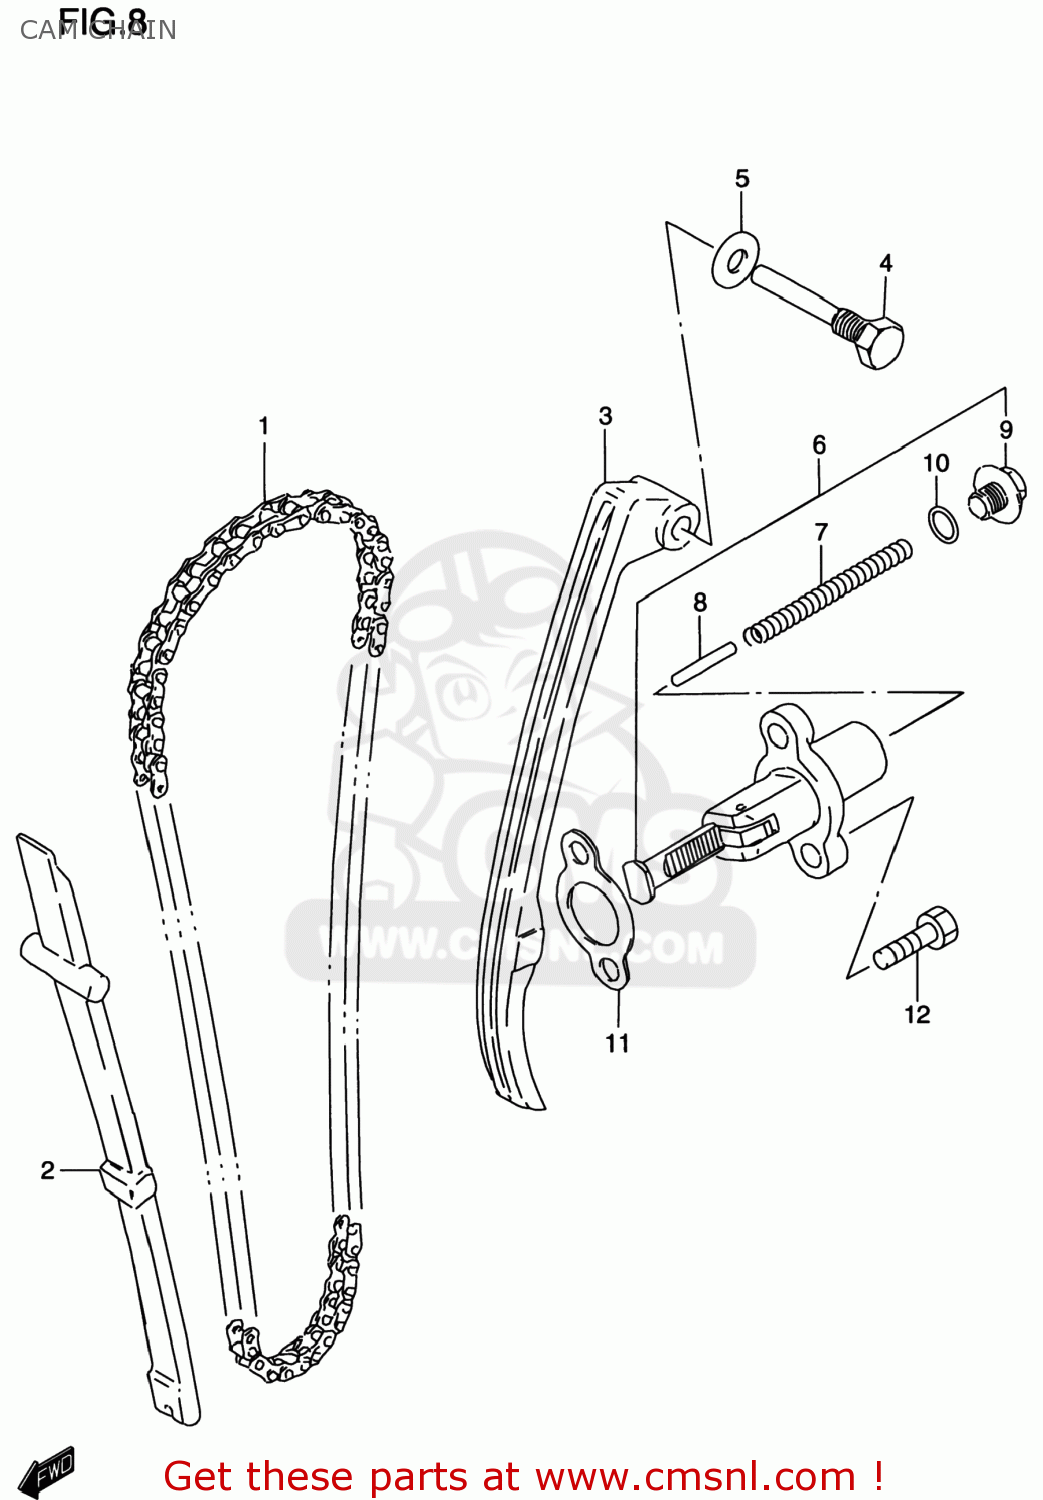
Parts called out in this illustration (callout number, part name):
1	CHAIN,CAMSHAFT DRIVE 102L
2	GUIDE,CAM CHAIN
3	TENSIONER,CAM CHAIN
4	BOLT,CAM CHAIN TENSIONER
5	GASKET 8.2X14X1 (NAS)
6	ADJUSTER ASSY,TENSIONER
7	SPRING
8	BAR
9	PLUG
10	O RING
11	GASKET,TENSIONER ADJUSTER (NAS)
12	BOLT
